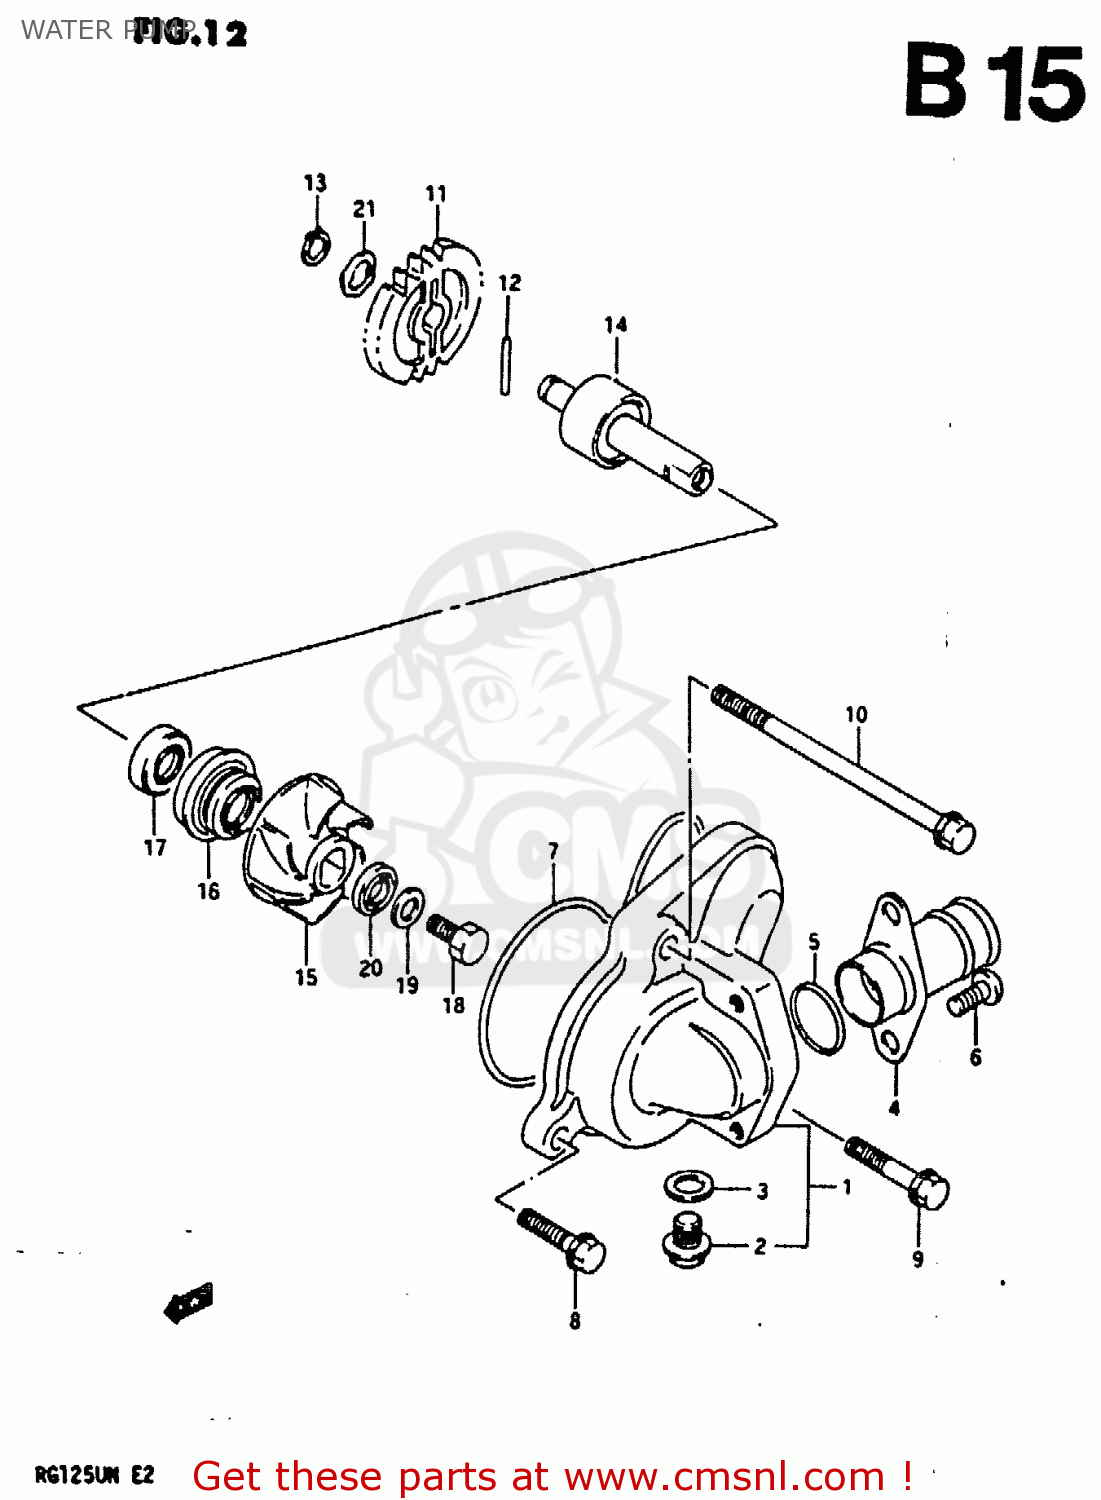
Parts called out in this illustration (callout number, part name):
1	CASE, WATER PUMP
2	BOLT,DRAIN
3	GASKET 8.2X14X1 (NAS)
4	CONNECTOR, WATER INLET
5	O RING(D:1.9,ID:18.8)
6	SCREW
7	O RING,WATER PUMP CASE
8	BOLT
9	BOLT
10	BOLT
11	GEAR,WATER PUMP DRIVEN
12	PIN(2.5X19.8)
13	CIRCLIP,10MM
14	SHAFT,WATER PUMP
15	IMPELLER,WATER PUMP
16	SEAL,MECHANICAL
17	SEAL,OIL(10X20X5)
18	BOLT(6X13)
19	WASHER
20	GASKET(6X15X2.2) (NAS)
21	WASHER
